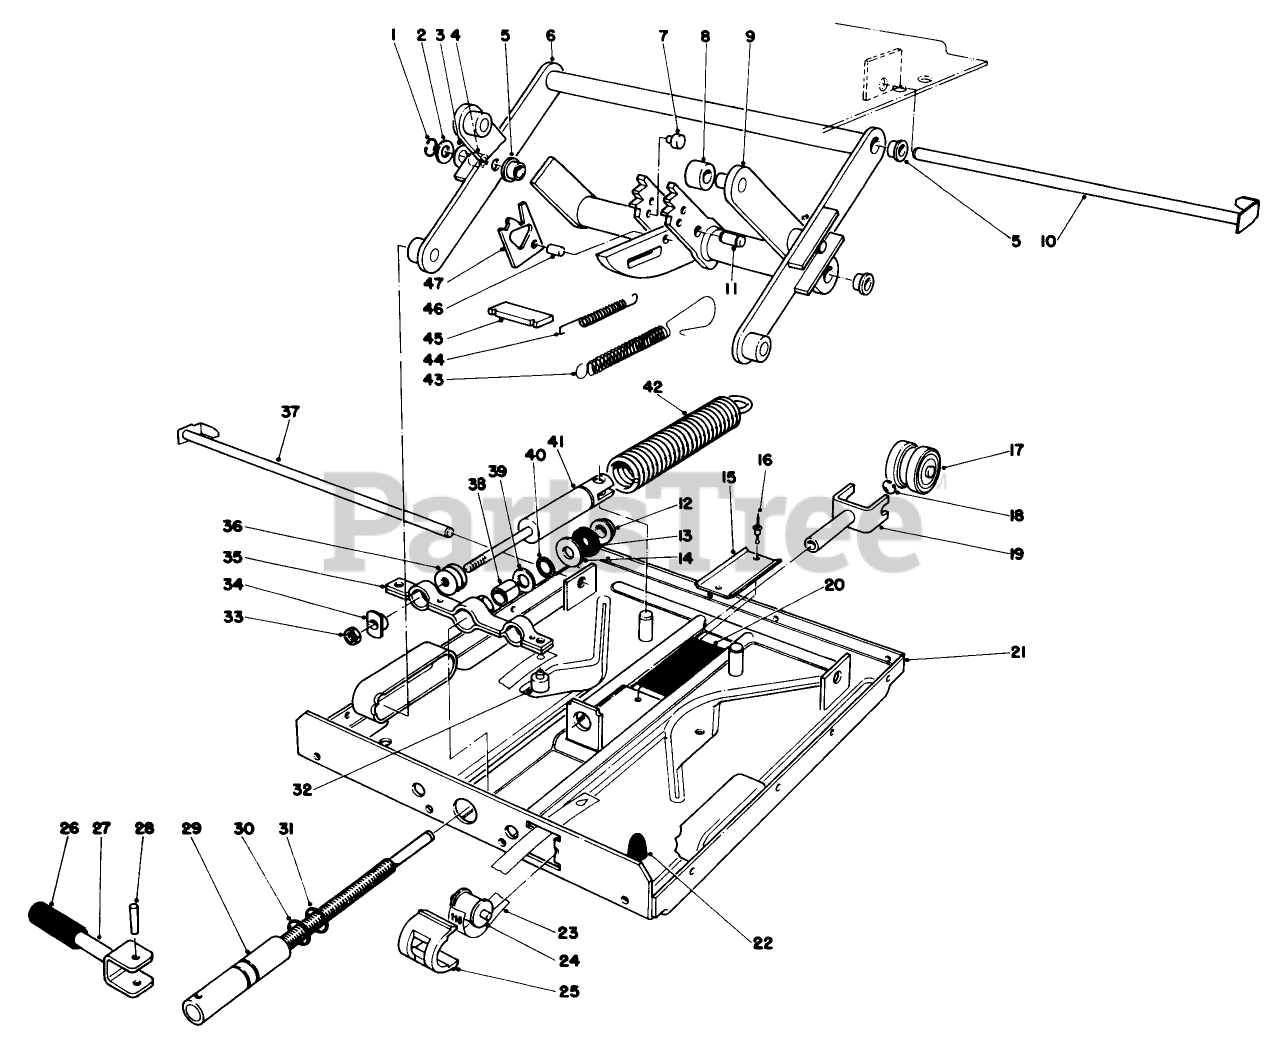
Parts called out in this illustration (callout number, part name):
1	Washer
2	Washer
3	Washer
4	WAVE WASHER
5	FRONT WEIGHT B
6	SPRING-BRAKE
8	LOCKNUT-CONDUIT
9	ASSY-QUADRANT
11	SPRING-EXTENSION
12	Sleeve
13	Idler Arm
14	Washer 8 MM
15	U-Track
16	Plate 4X10MM
17	Trible-Bearing
18	Washer
20	Rubber Plate
21	Lower Suspension Plate- Complete (Incl. Ref. # 15-16 & 20)
22	Bumper
23	PLATE-HOODSTAND REAR
24	Roller
25	Guide Sleeve
26	Handle
27	Toggle
28	Grooved Pin 5X28MM
30	Rubber Ring 14MM Black
31	Rubber Ring 14MM Red
33	ASSY-DIFFERENTIAL
34	BUSHING PTO PIVOT
35	Spring Bracket
36	DECAL HOOD RH
37	SPACER-BUSHING
38	Sleeve 14x1x19MM
39	Washer
40	Thrust Needle Bearing
41	Brake Pad
42	Coil Spring
43	Coil Spring
44	Coil Spring
45	WASHER
47	Footrest RH
